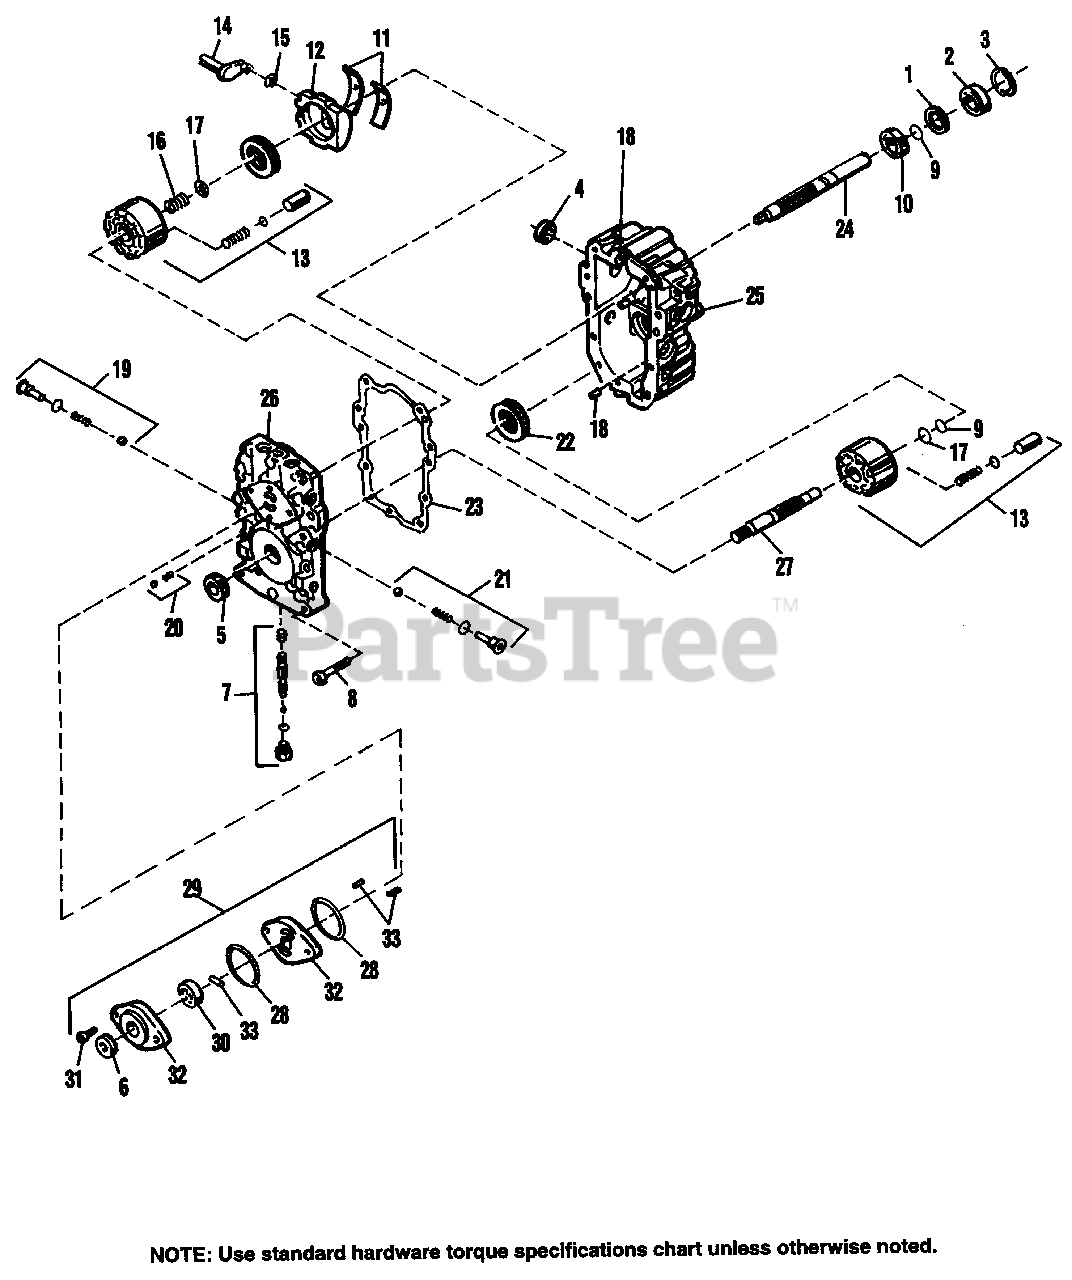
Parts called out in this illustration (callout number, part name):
1	SPACER
2	SEAL
3	RETAINING RING
4	SEAL
5	SEAL
6	SEAL
7	BYPASS VALVE KIT
8	CAPSCREW, Socket Hd.
9	RETAINING RING
10	BEARING. Shaft
11	CRADLE, Bearing
12	VARIABLE SWASHPLATE
13	BLOCK ASSY.
14	TRUNNION ARM
17	THRUST WASHER
19	CHECK VALVE KIT, RH
20	CHARGE RELIEF KIT
21	CHECK VALVE KIT, LH
22	THRUST BEARING ASSY.
23	GASKET, Center Section
25	PUMP HOUSING KIT
26	CENTER SECTION KIT
27	MOTOR SHAFT
28	O-RING
29	CHARGE PUMP KIT
30	GEROTOR ASSY.
31	CAPSCREW, 6M x 20
32	SPACER PLATE
